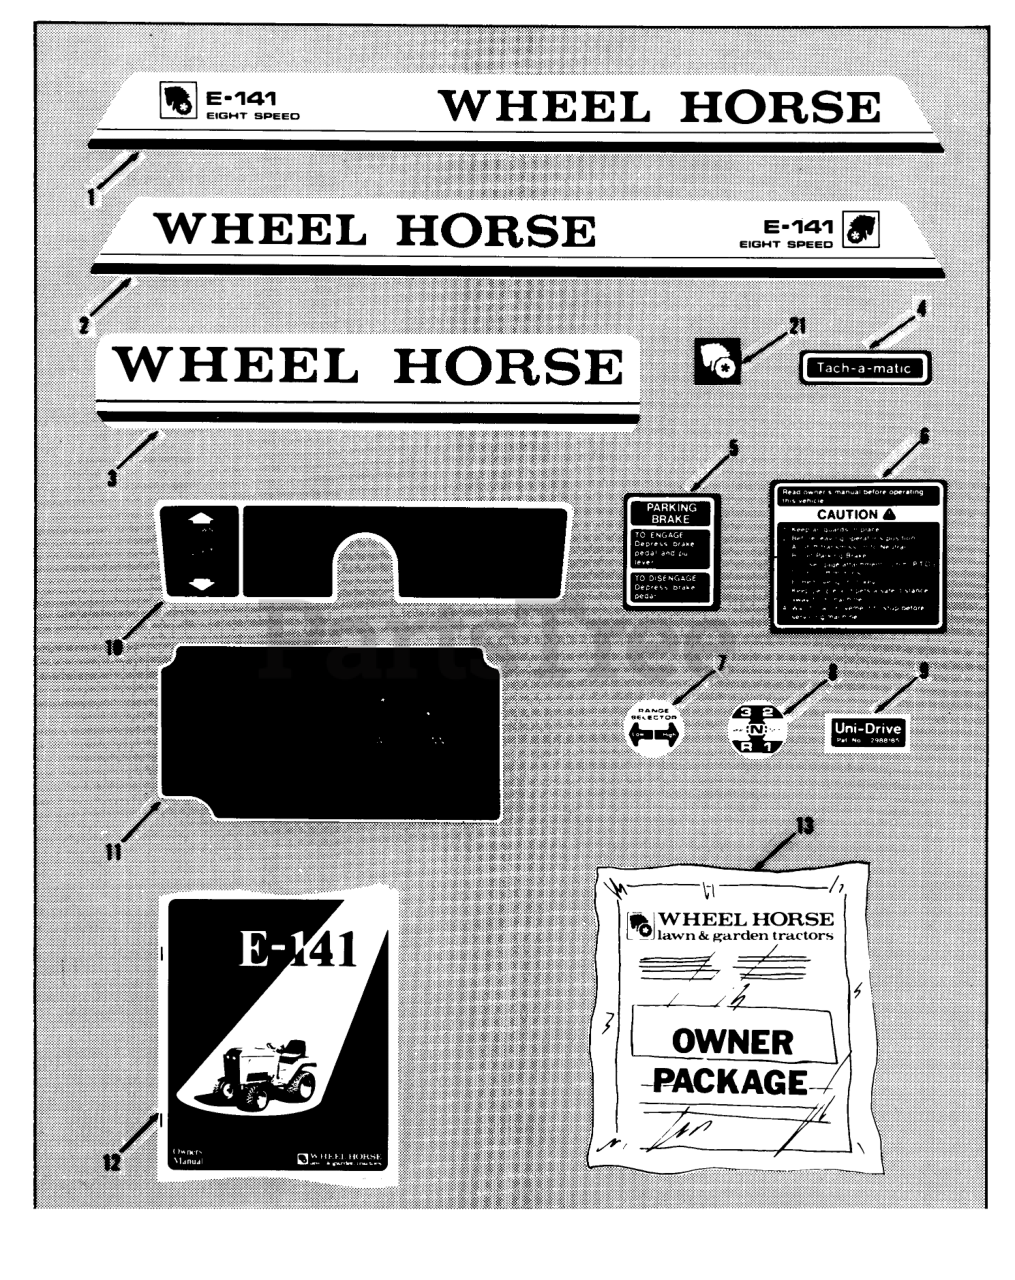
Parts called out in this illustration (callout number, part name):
1	Decal LH E-141 8-Speed
2	Decal RH E-141 8-Speed
3	Decal-Rear
4	DECAL-TACHAMATIC
5	DECAL-PARKING BRAKE
6	DECAL-CAUTION
7	DECAL HI-LO
8	DECAL-SHIFT
9	Decal-Unidrive
10	Decal-Control Housing
11	Decal-Rear Plate
12	Tractor Owner-s Manual
13	Loose Parts Package E-141
21	DECAL-LOGO
